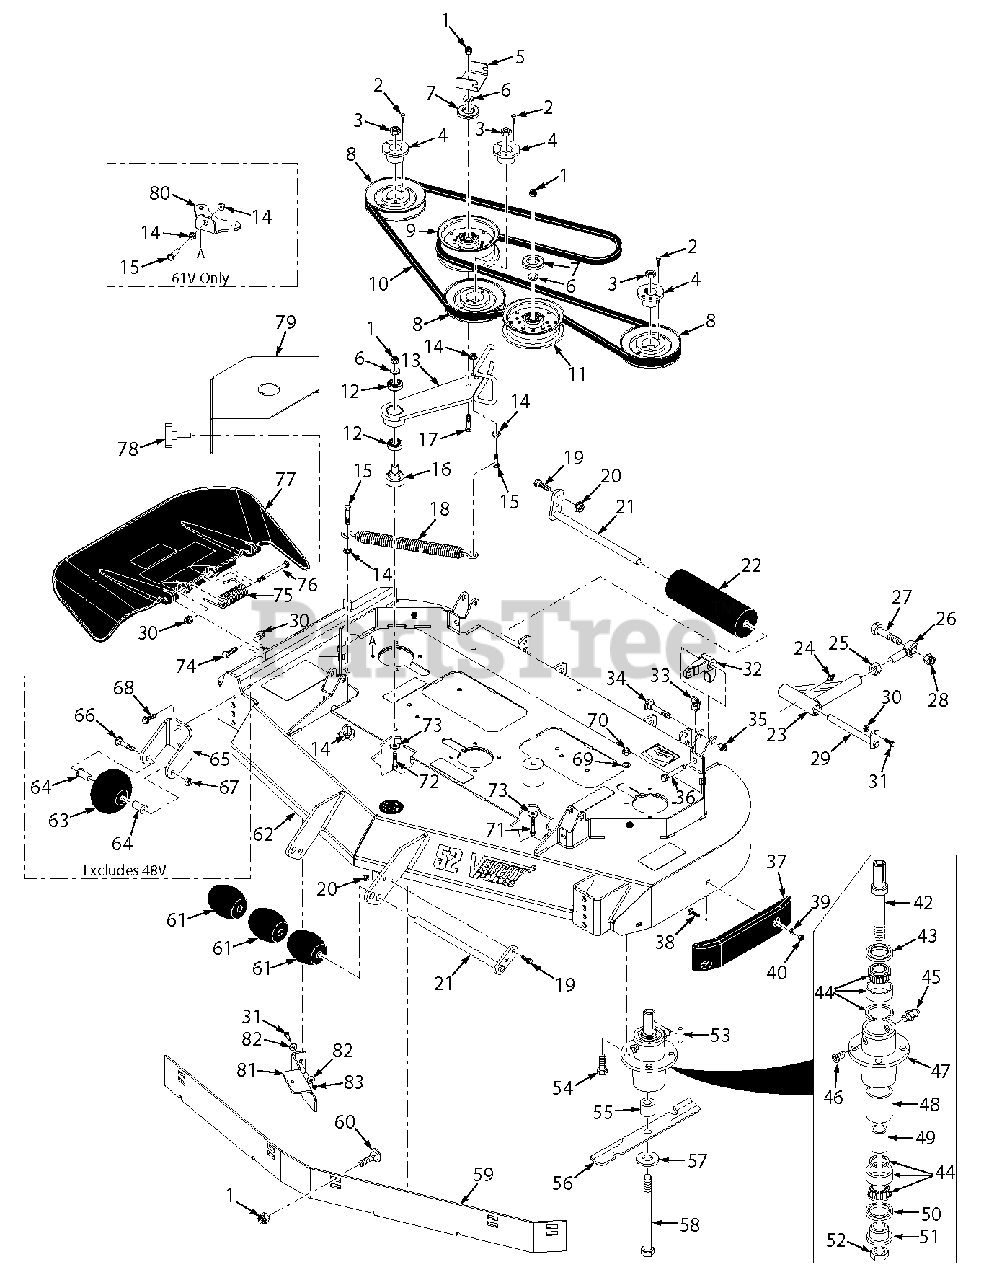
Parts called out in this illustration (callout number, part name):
1	Nut, Elastic Stop 3/8-16
2	Bolt, Hex Head 1/4-20 x 1"
3	Nut, 5/8-11
4	Tapered Hub
5	Bracket, Belt Guide
6	Flatwasher, 3/8-.391 x .938 x .105 HD
7	Dust Shield
8	Pulley, 5.13" Dia. - 48V
8	Pulley, 5.73" Dia. - 52V
8	Pulley, 6.32" Dia - 61V
9	Pulley, 5" Idler
10	Belt, Cutter Deck - 48V
10	Belt, Cutter Deck - 52V
10	Belt, Cutter Deck - 61V
11	Pulley, 5" Idler
12	Bearing
13	Idler Arm Assy. - 48V
13	Idler Arm Assy. - 52V
13	Idler Arm Assy. - 61V
14	Nut, Serrated Flange 3/8-16
15	Bolt, Hex Head 3/8-16 x 1-1/2"
16	Pivot, Idler
17	Bolt, Hex Head 3/8-16 x 3-1/4"
18	Spring
19	Bolt, Hex Head 5/16-18 x1"
20	Nut, Flange Elastic Stop 5/16-18
21	Shaft Weldment
22	Guide Roller
23	Pusharm Assy, LH
23	Pusharm Assy, RH
24	Grease Fitting, 90 Degree
25	Nut, 5/8-18 UNF
26	Rod End, 5/8 Male RH
27	Bolt, Hex Head 5/8-11 x 4-1/2"
28	Nut, Elastic Stop 5/8-11
29	Shaft Weldment, Pusharm Mounting
30	Nut, Elastic Stop 5/16-18
31	Bolt, Hex Head 5/16-18 x 1"
32	Lever, Deck Level
33	U-Nut, 3/8-16
34	Bolt, Carriage 7/16-14 x 2-1/4"
35	Nut, Elastic Stop 7/16-14
36	Bolt, Hex Head 3/8-16 x 2" Special Lock
37	Pad, Wear
38	Bolt, Carriage 5/16-18 x 3/4"
39	Flatwasher, 5/16-.344 x .688 x .065
40	Nut, Center Lock 5/16-18
41	Spindle Assembly
42	Spindle Shaft
43	Seal, Cutter Spindle
44	Bearing, Tapered
45	Grease Fitting
46	Relief Fitting, Cutter Spindle
47	Spindle Housing
48	Spacer, Outside
49	Spacer, Inside
50	Seal, Cutter Spindle
51	Spindle Bushing
52	Nut, 1.06 - 18
53	Key, 1/4 x 1/4 x 2"
54	Bolt, Hex Head 5/16-18 x 1-1/2"
55	Spacer, Spindle Bottom
56	Cutter Blade, 16-1/2" (48V)
56	Cutter Blade, 18" (52V)
56	Cutter Blade, 21" (61V)
57	Flatwasher, 5/8-.688 x 1.75 x .134 HD
58	Bolt, Hex Head 5/8-11 x 9-1/2"
59	Baffle, Flange - 48V
59	Baffle, Flange - 52V
59	Baflle, Flange - 61V
60	Bolt, Carriage 3/8-16 x 1"
61	Wheel, Anti-Scalp
62	Cutter Deck w/Decals - 48V
62	Cutter Deck w/Decals - 52V
62	Cutter Deck w/Decals - 61V
63	Wheel, Anti-Scalp
64	Bushing, Bronze
65	Bracket, Anti-Scalp Wheel
66	Bolt, Carriage 3/8-16 x 4"
67	Nut, Center Lock 3/8-16
68	Bolt, Hex Head Serrated Flange 3/8-16 x 1"
69	Lockwasher, 5/16"
70	Nut, Elastic Stop 5/16-18
71	Bolt, Hex Head 3/8-16 x 5"
72	Bolt, Hex Head 3/8-16 x 3-1/4"
73	Flatwasher, 3/8-.406 x 2.25 x .1875
74	Bolt, Hex Head 5/16-18 x 1-3/4"
75	Spring, Discharge Chute
76	Bolt, Hex Head 5/16-18 x 4-3/4"
77	Discharge Chute Assy. - 48V
77	Discharge Chute Assy. - 52V
77	Discharge Chute Assy. - 61V
78	Knob w/Stud
79	Belt Cover, RH - 48V
79	Belt Cover, LH - 48V
79	Belt Cover - 52V
79	Belt Cover, RH - 61V
79	Belt Cover, LH - 61V
80	Anchor Bracket - 61V
81	Turbo Baffle - 48V / 52V
81	Turbo Baffle - 61V
82	Flatwasher, 5/16-.375 x .875 x .083
83	Nut, Elastic Stop 5/16-18
